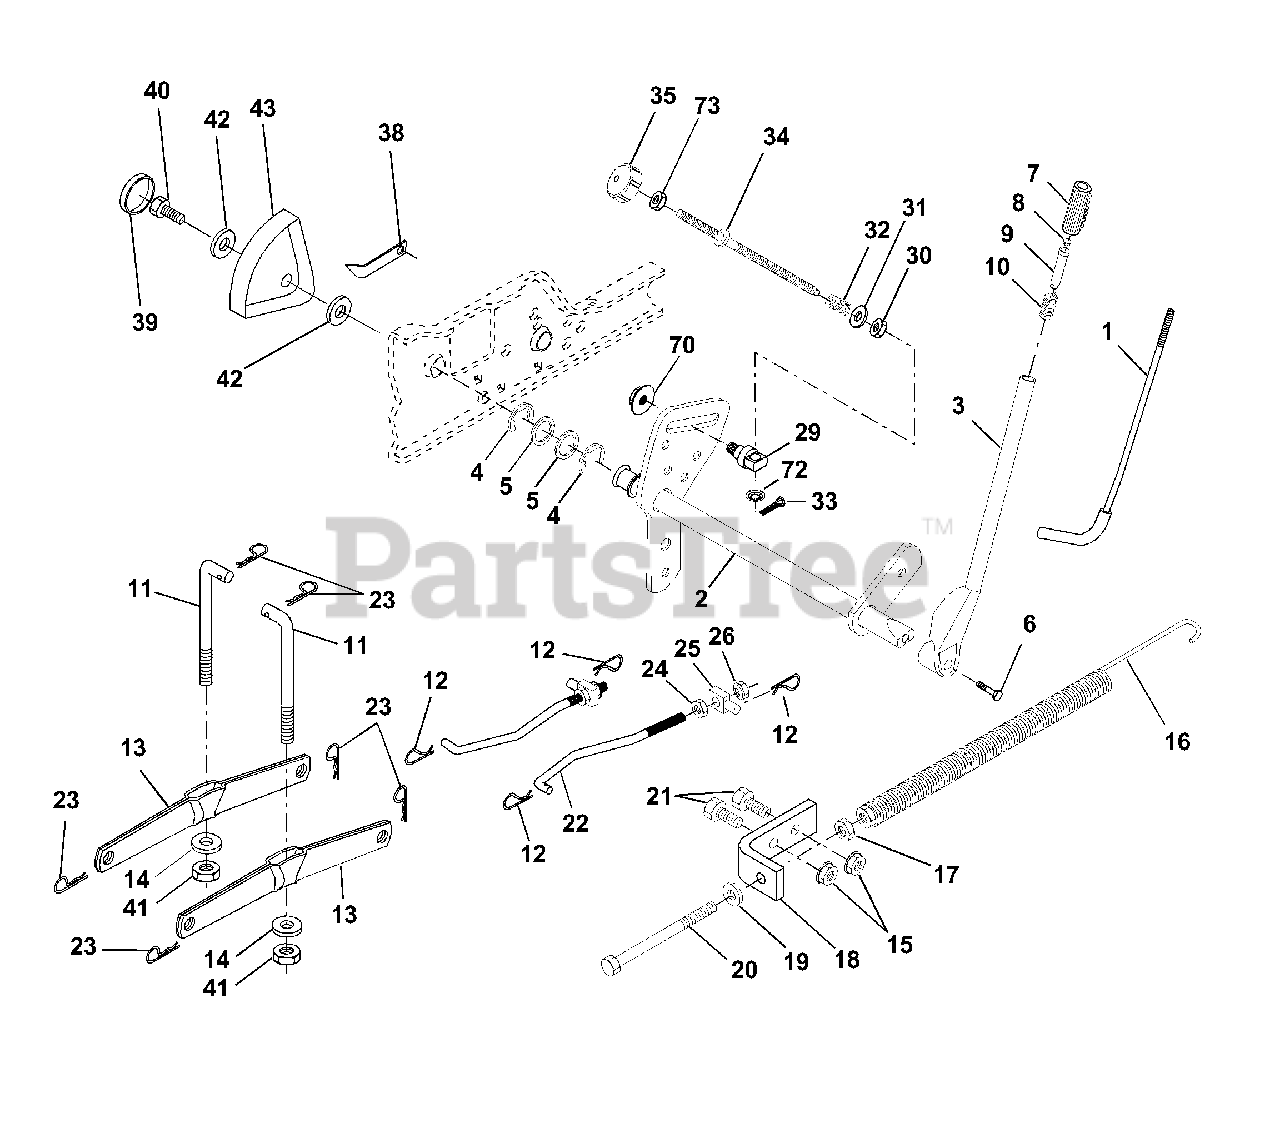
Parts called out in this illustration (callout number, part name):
1	Rod Asm., Lever
2	Shaft Asm., Lift Vgt
3	Lever Asm., Lift Rh
4	E-Ring Truarc #5133-87
5	Washer 29/32 x 1-1/4 x 16 Ga.
6	Bolt, Fin Hex 3/8-16 x 1-1/2
7	Grip, Handle Fluted
8	Button, Plunger
9	Plunger, Lever Lift
10	Spring 2-1/8"
11	Link Lift
12	Retainer, Spring
13	Arm, Suspension Vgt
14	Bearing, Pvt. Lift Spherical
15	Nut, Crownlock 3/8-16 Unc
16	Spring Asm., Assist Lift
17	Nut, Hex Jam 3/8-16 Unc
18	Bracket, Spring Assist
19	Washer 13/32 x 13/16 x 16 Ga.
20	Bolt, Adjust Spring Assist
21	Bolt, Fin Hex 3/8-16 x 1
22	Link, Front
23	Retainer, Spring
24	Nut, Jam Hex 1/2-13 Unc
25	Trunnion
26	Nut Crownock 1/2-13 Unc
29	Trunnion Inf. Height
30	Nut, Special
31	Washer 13/32 x 5/8 x 16 Ga.
32	Spring, Compression Inf Hgt
33	Pin, Cotter 3/32 x 1/2
34	Rod, Adj Lift
35	Knob, Inf 3/8-16 Unc
38	Pointer, Height Indicator
39	Plug, Hole
40	Screw Thdrol 5/16-18 x 3/4
41	Nut, Crownlock 3/8-24
42	Washer 11/32 x 1-1/2 x 10 Ga.
43	Scale, Indicator Height
70	Nut, Hexflange Lock
72	Nut Push Phos. & Oil
